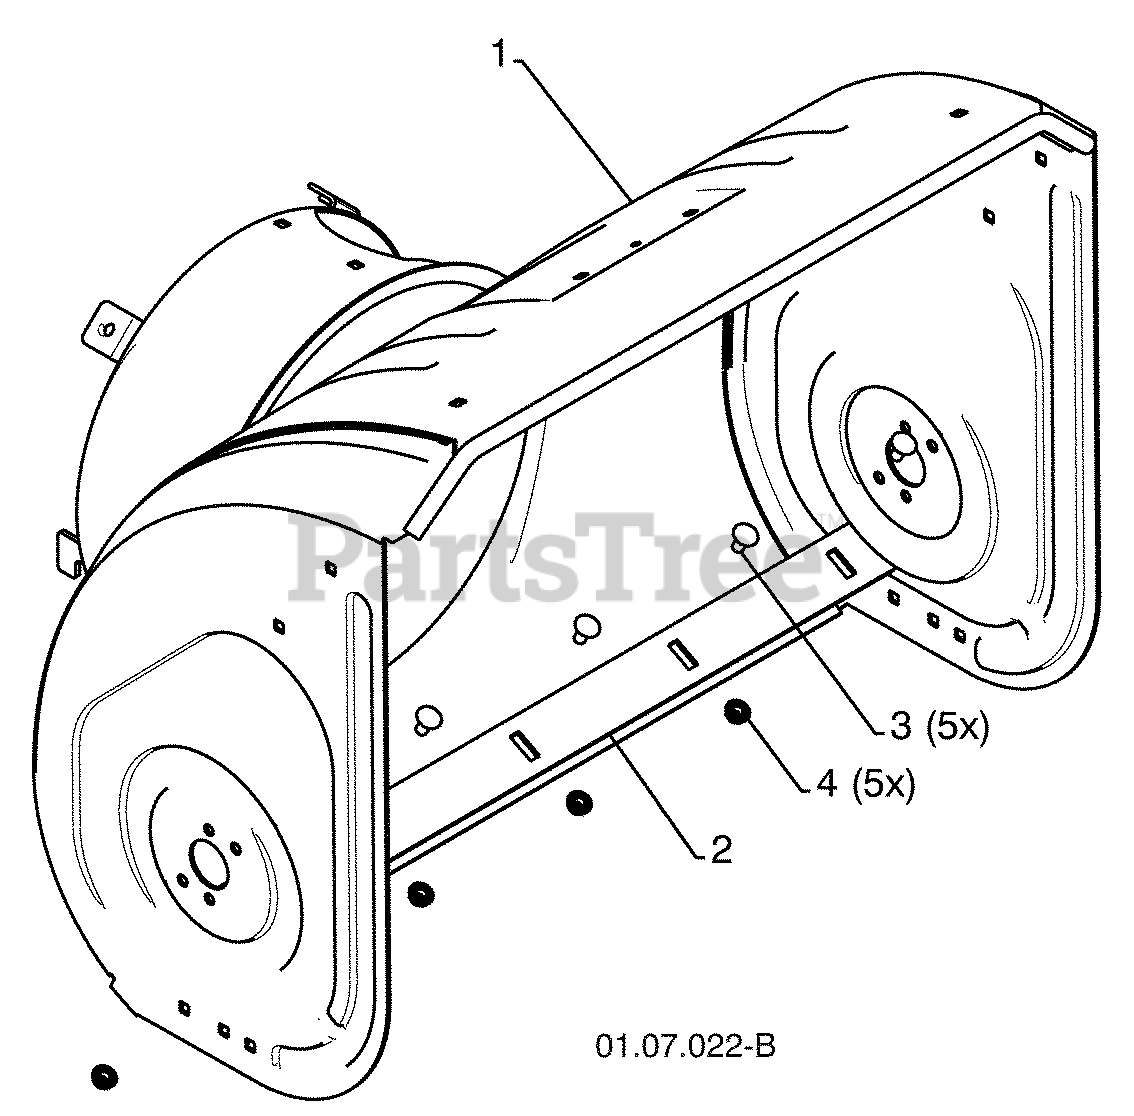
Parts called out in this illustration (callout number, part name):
1	AUGER HOUSING
2	SCRAPPER BAR
3	CARRIAGE BOLT 5/16-18 X .625
4	NUT 5/16-18
